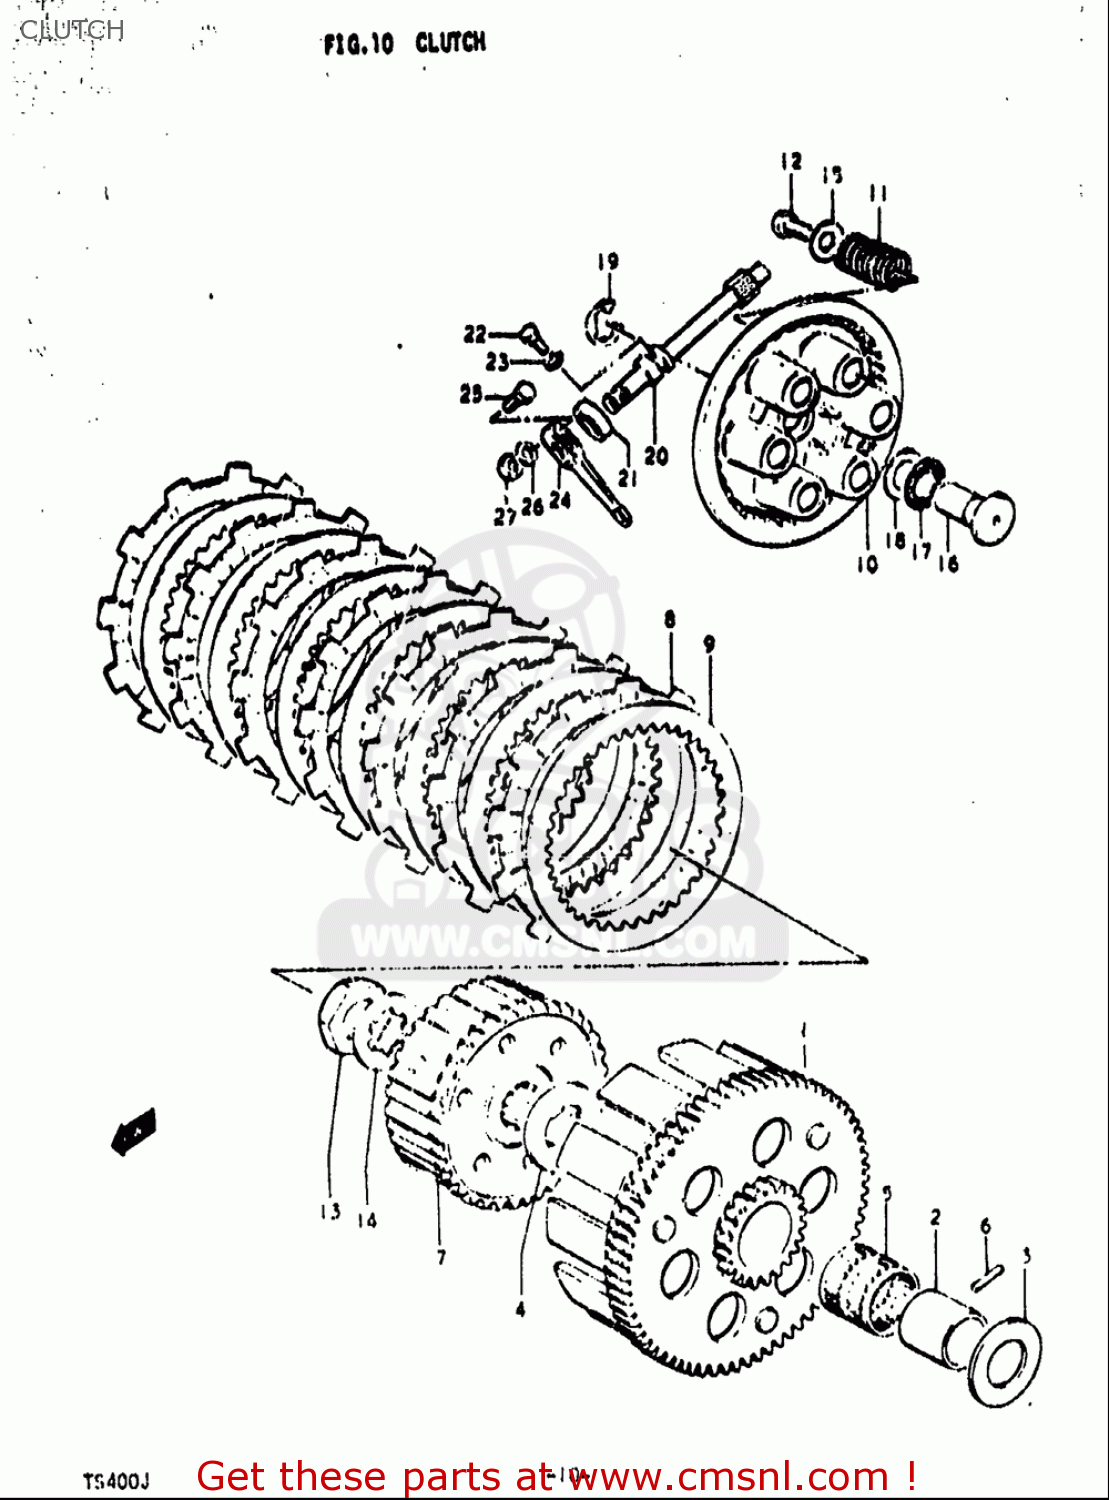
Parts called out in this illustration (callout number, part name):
2	SPACER
3	WASHER
5	BEARING
8	PLATE,CLUTCH DRIVE(T:3.5) (NAS)
9	PLATE,CLUTCH DRIVEN(T:2.0) (NAS)
10	DISC,CLUTCH PRESSURE
11	SPRING
12	BOLT
13	NUT
14	WASHER,LOCK
15	WASHER(6.5X20X1.6)
16	RACK,CLUTCH RELEASE
17	BEARING(15X28X2)
18	WASHER(15.5X28X1)
19	E RING
20	PINION,CLUTCH RELEASE
21	SEAL,OIL (12X22X9)
22	BOLT(6X12)
23	WASHER
24	ARM,CLUTCH RELEASE
25	BOLT
26	WASHER
27	NUT
